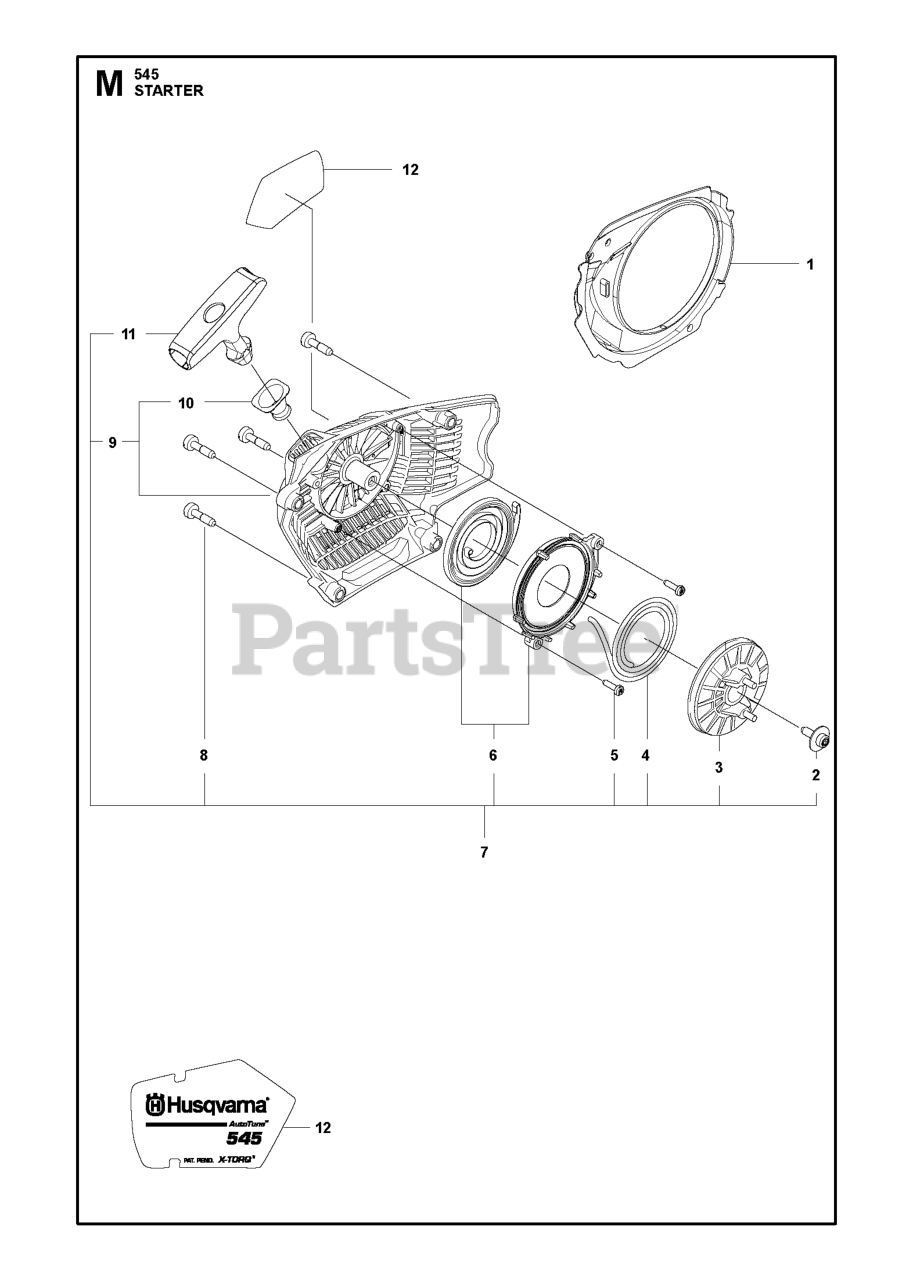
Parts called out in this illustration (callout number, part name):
1	COOLING AIR CONDUCTOR
2	SCREW ITXSCT MT5X16 10.9 TBO
3	STARTER PULLEY ASSY
4	STARTER ROPE
5	SCREW CITXPANT
6	SPRING CASSETTE ADDY
7	STARTER ASSY
8	SCREW CITXPANMO
